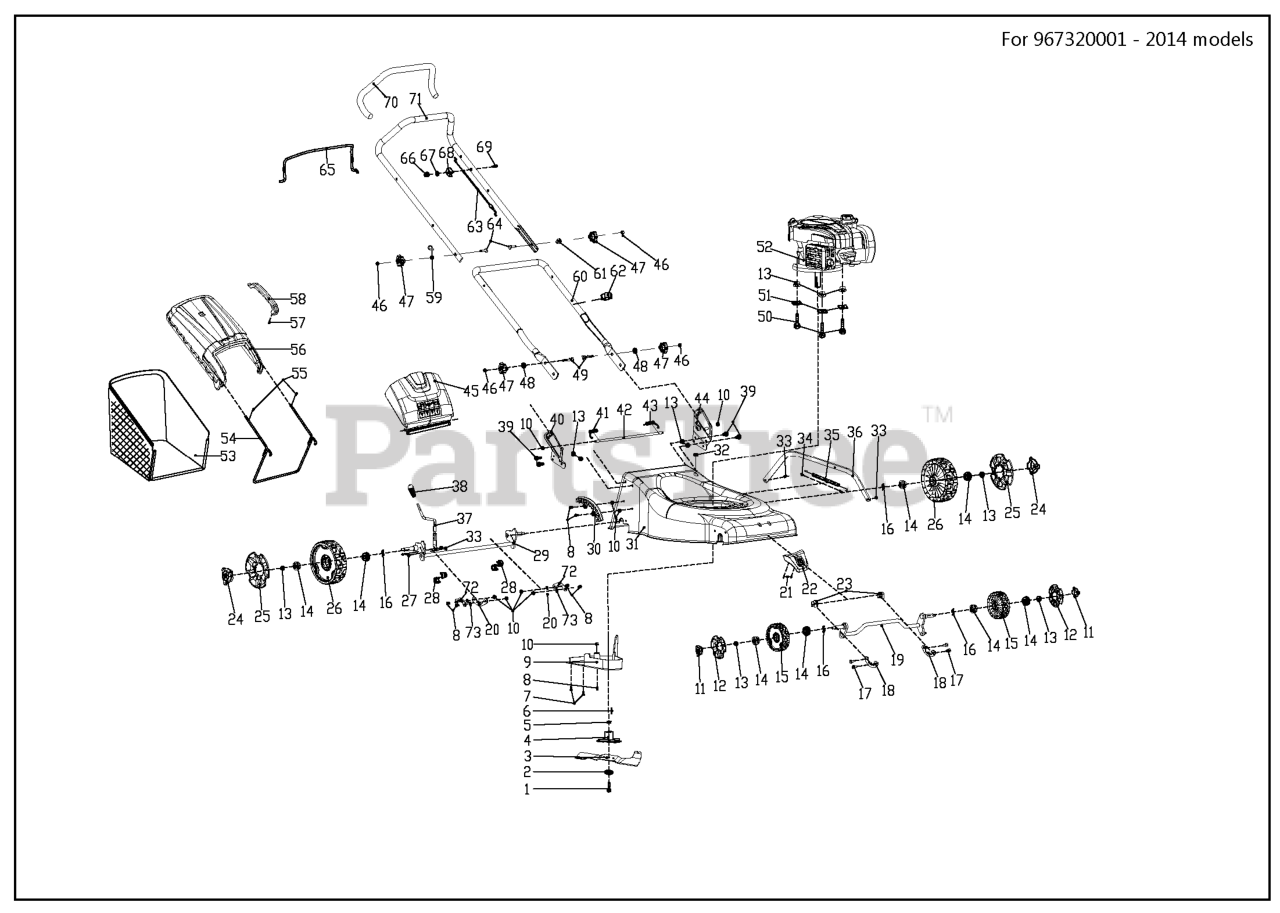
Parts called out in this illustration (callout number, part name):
8	SCREW M6*16 #26800204601
10	LOCK NUT M6,GB/T6187.1-2000 #2
11	WHEEL COVER 6" #25340700101
13	LOCKING BOLT M8,GB6187.1 #2680
16	WASHER Ï?12 #26800706202
20	FIXING PLATE #26300124401
24	WHEEL COVER 8" #25341000101
25	WHEEL COVER 8" #25341100101
26	WHEEL #25341300101
27	WASHER M6*14 #26800203001
28	COVER AXLE #25235300101
30	SEGMENT #25214200102
33	LOCKING BOLT M6,GB889.1 #26800
34	TUBING #29000300101
35	SPRING #26801103903
38	KNOB HEIGHT ADJUSTMENT #25341
39	BOLT M8*16 #26800606401
41	SPRING #26801125501
43	BRACKET #26801125401
46	HEXAGON NUT #26800502301
47	KNOB #25341500101
53	GRASSBAG #25100173001
54	BRACKET #26300299201
56	COVER GRASS CATCHER #253417001
57	SCREW ST4.8*19,GB845 #26800104
58	HANDLE #25341800101
72	FIXING PLATE #26300314601
73	O-RING #25100175201
